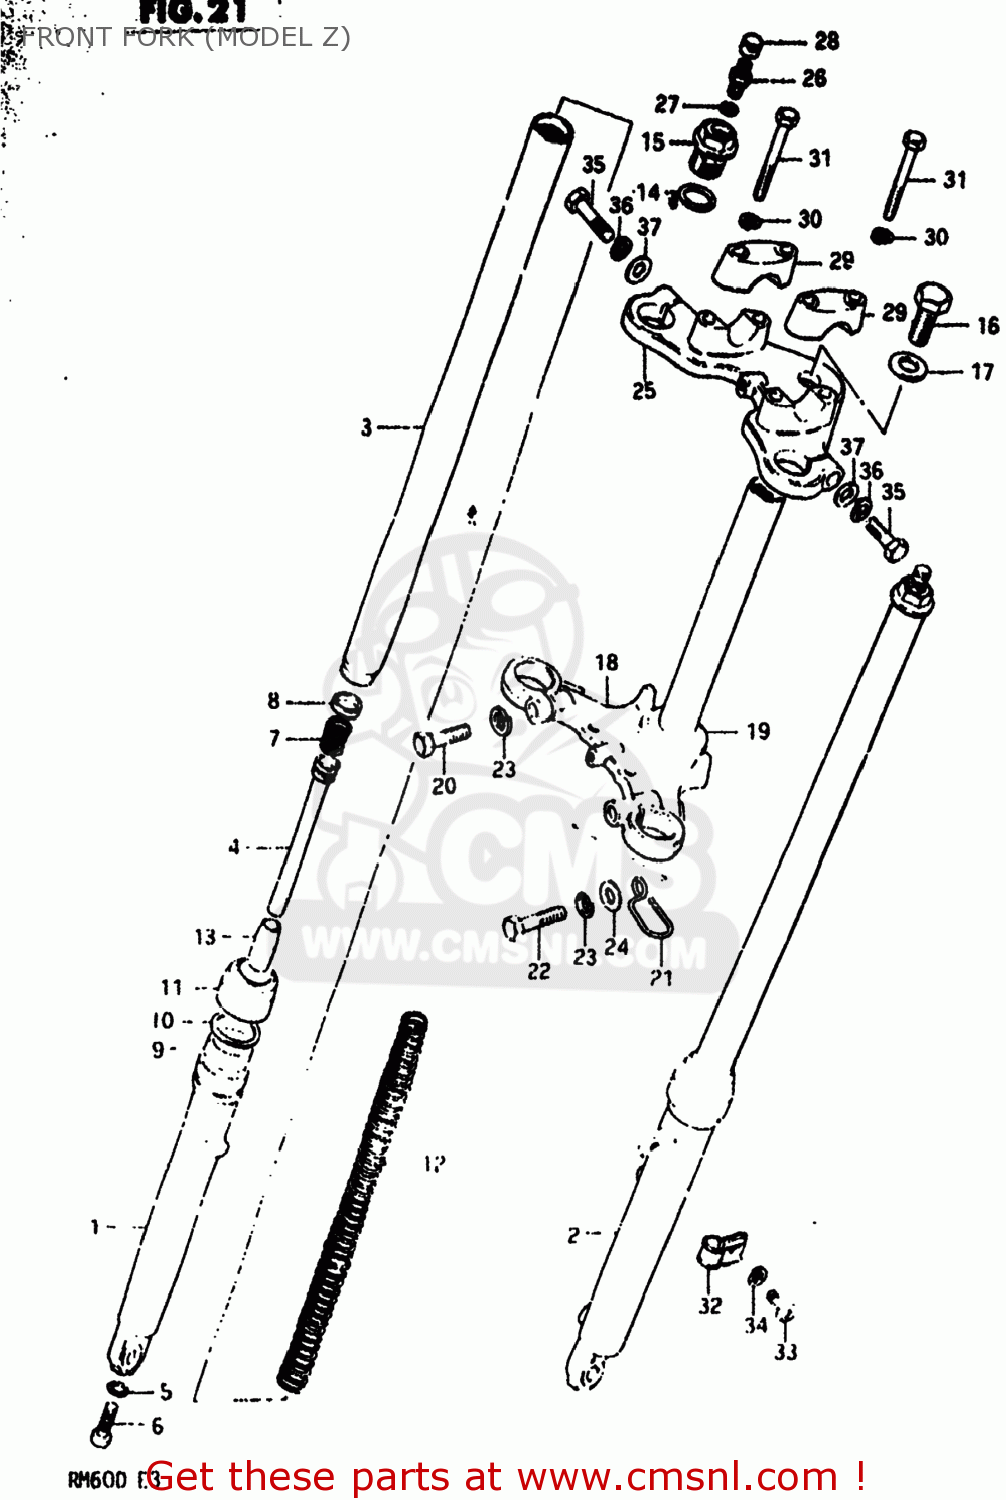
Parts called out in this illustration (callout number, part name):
1	TUBE,OUTER,RIGHT
2	TUBE,OUTER,LEFT
3	TUBE,FORK,INNER
4	CYLINDER,FRONT FORK
5	GASKET (NAS)
6	BOLT(8X27)
7	SPRING,REBOUND
8	RING,PISTON
9	OIL SEAL,FRONT FORK
10	CIRCLIP,FORK OIL SEAL
11	DUST SEAL
12	SPRING
13	PIECE,OIL LOCK
14	O RING
15	CAP,FORK
16	BOLT
17	WASHER(10.5X30X2.3)
18	STEM,STEERING
19	RACE,STEERING OUTER LWR
20	BOLT 10X30
21	CLAMP,METER CABLE
22	BOLT,M10X1.25X
23	LOCK WASHER
24	WASHER
25	HEAD,STEERING STEM
26	VALVE,AIR
27	O-RING
28	CAP,VALVE AIR
29	HOLDER,HANDLEBAR
30	LOCK WASHER
31	BOLT
32	CLIP,CABLE
33	SCREW
34	LOCK WASHER
35	BOLT 8X40
36	LOCK WASHER
37	WASHER
